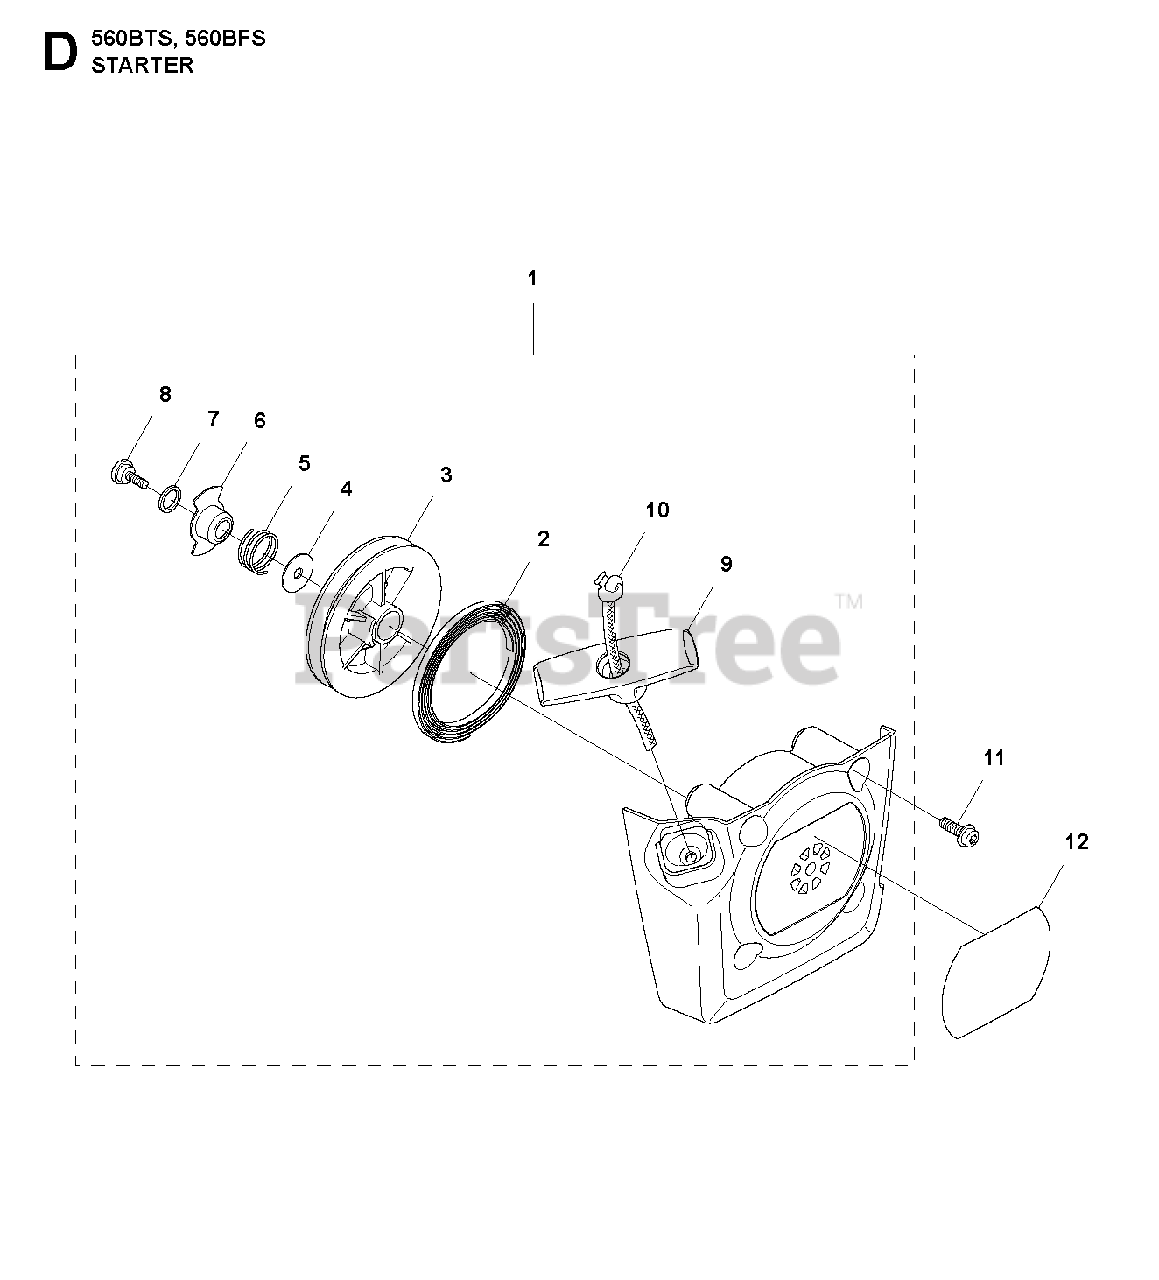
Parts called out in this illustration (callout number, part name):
1	STARTER ASSY
2	SPRING
3	REEL
4	WASHER
5	SPRING FRICTION
6	PLATE
7	WASHER
8	SCREW
9	HANDLE
10	ROPE
12	STARTER DECAL
12	DECAL RECOIL
